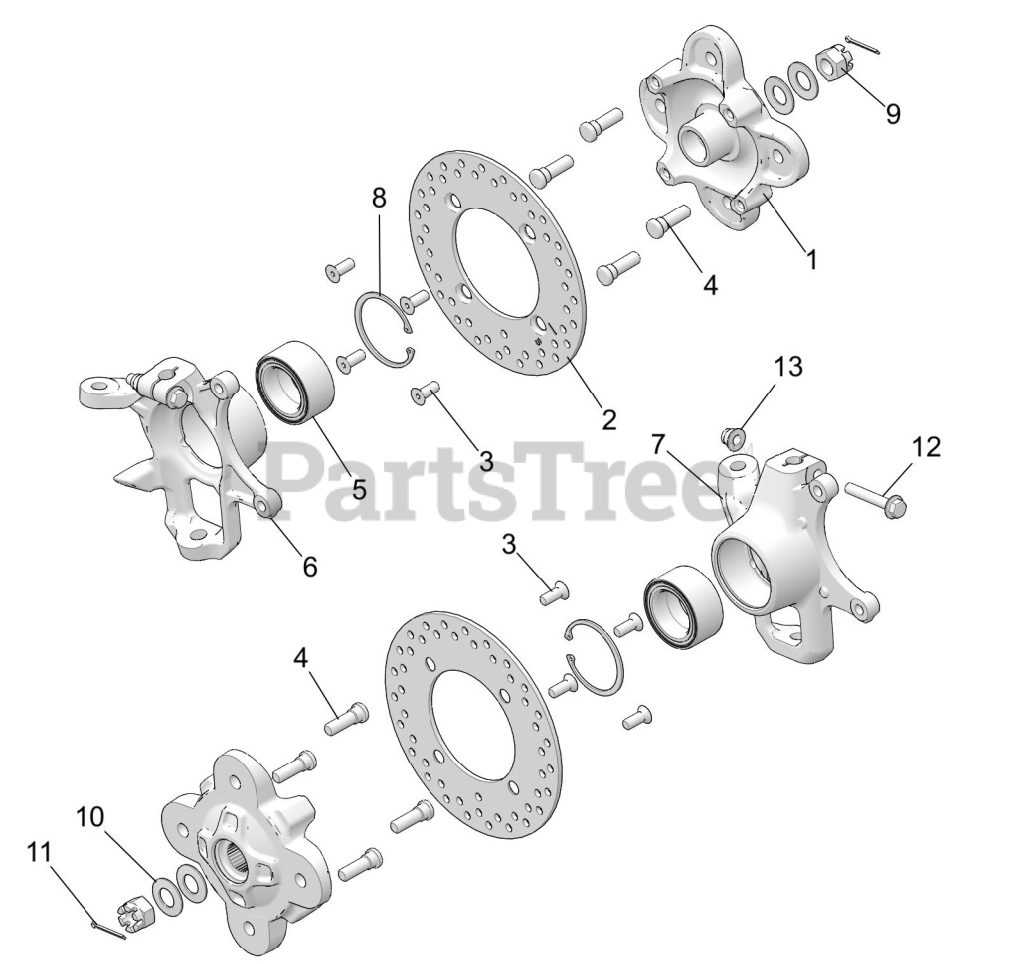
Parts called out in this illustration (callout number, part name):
1	HUB-WHEEL-FRONT MACH- BLK
2	ROTOR- BRAKE
3	SCR-M10X1.5X20 8.8 TXCS FL ZOD
4	STUD-WHEEL-M12-1.5
5	BEARING-BALL-SEALED-44X72X33.1
6	KNUCKLE-FRONT-LH
7	KNUCKLE-FRONT-RH
8	RING- RETAINING- INTERNAL
9	NUT-M18X1.5-CASTLE-ZINC/YELLOW
10	WASHER- CONE
11	PIN- COTTER
12	SCR-HXFL-M10X1.25X60 10.9 ZOD
13	NUT-M10X1.25-FLG-NYLOC-OLIVE D
